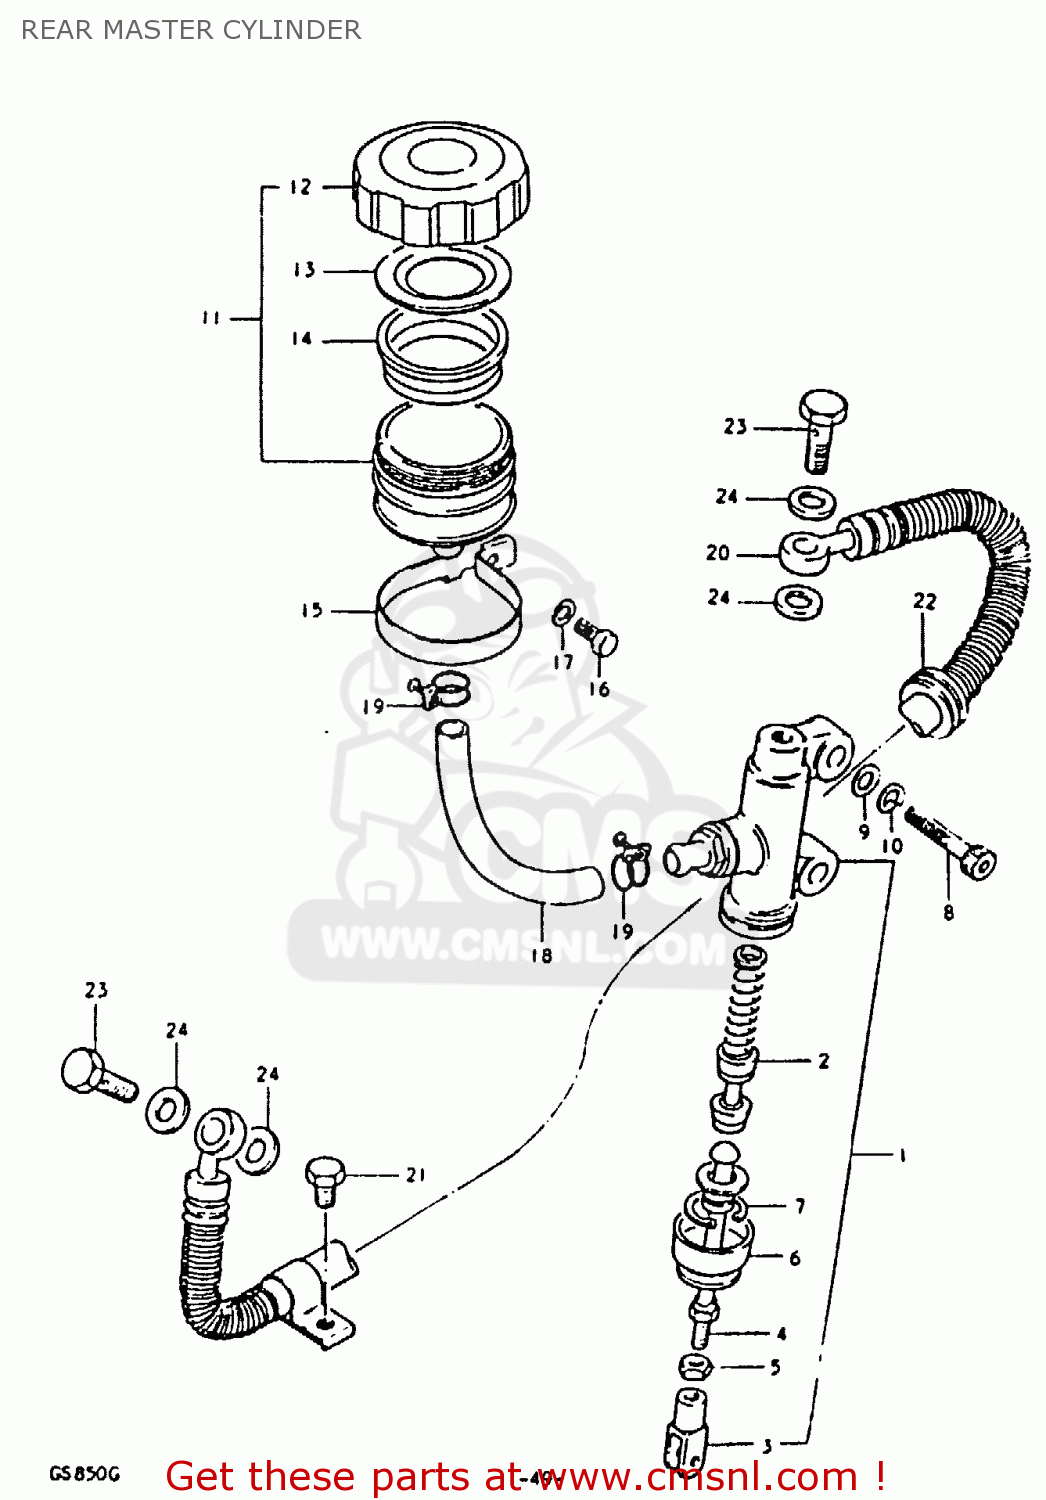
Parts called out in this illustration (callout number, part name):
1	CYLINDER ASSEMBLY,REAR MASTER
2	PISTON/CUP SET
3	YOKE
4	ROD,PUSH
5	NUT
6	BOOT
7	CIRCLIP
8	BOLT
9	WASHER
10	LOCK WASHER
11	TANK ASSEMBLY,RESERVOIR
12	CAP
13	PLATE,DIAPHRAGM
14	DIAPHRAGM
15	CLAMP
16	BOLT, UPPER
17	LOCK WASHER
18	HOSE,RESERVOIR TANK
19	CLAMP
20	HOSE,REAR BRAKE
21	BOLT
22	GROMMET
23	BOLT UNION
24	WASHER
